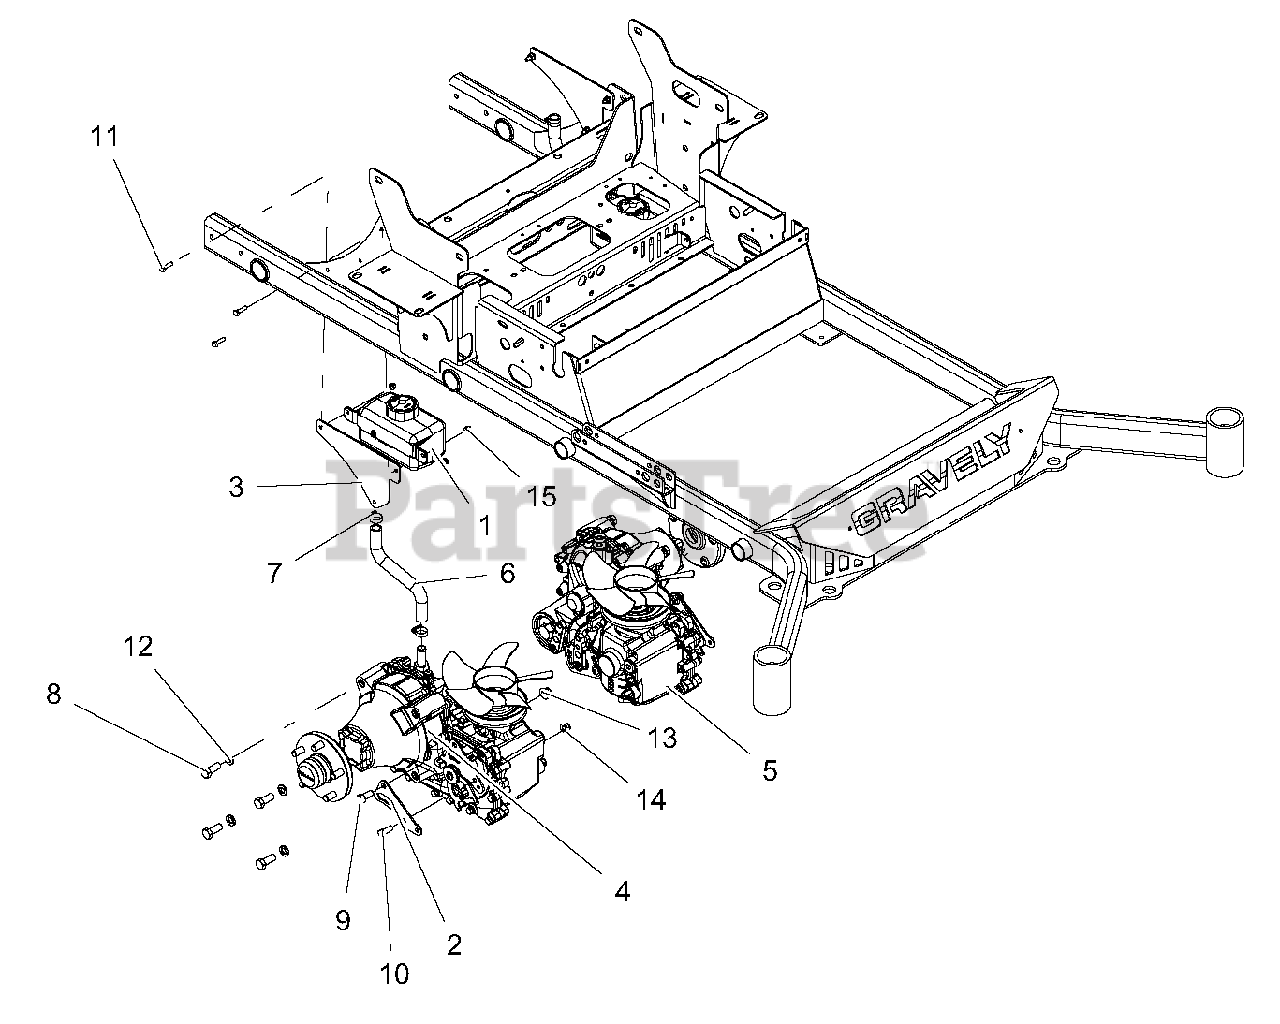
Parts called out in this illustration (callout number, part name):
1	TANK, HYD 1000ML
2	BRKT., CONTROL MTG-BLACK
3	PLATE, HYDRO OVERFLOW TANK MTG
4	TRANS, R.H. HG ZT-5400
5	TRANS, LH HG ZT-5400
6	HOSE, HYDRO OVERFLOW
7	CLAMP, .88 DIA HOSE
8	BLT-HEX .50-13X1.25 GR5 YWZC
9	BLT-HEX .44-14X1.00 GR5 YWZC
10	BLT-HEX .38-16X1.00 GR5 YWZC
11	BLT-HEX .25-20X1.00 GR5 YWZC
12	@WSHR-LK .50X.125 REG YWZC
13	NUT-LK-NYL-FLG .44-14 YWZC
14	NUT-LK-NYL-FLG .38-16 YWZC
15	NUT-LK-NYL-FLG .25-20 YWZC
